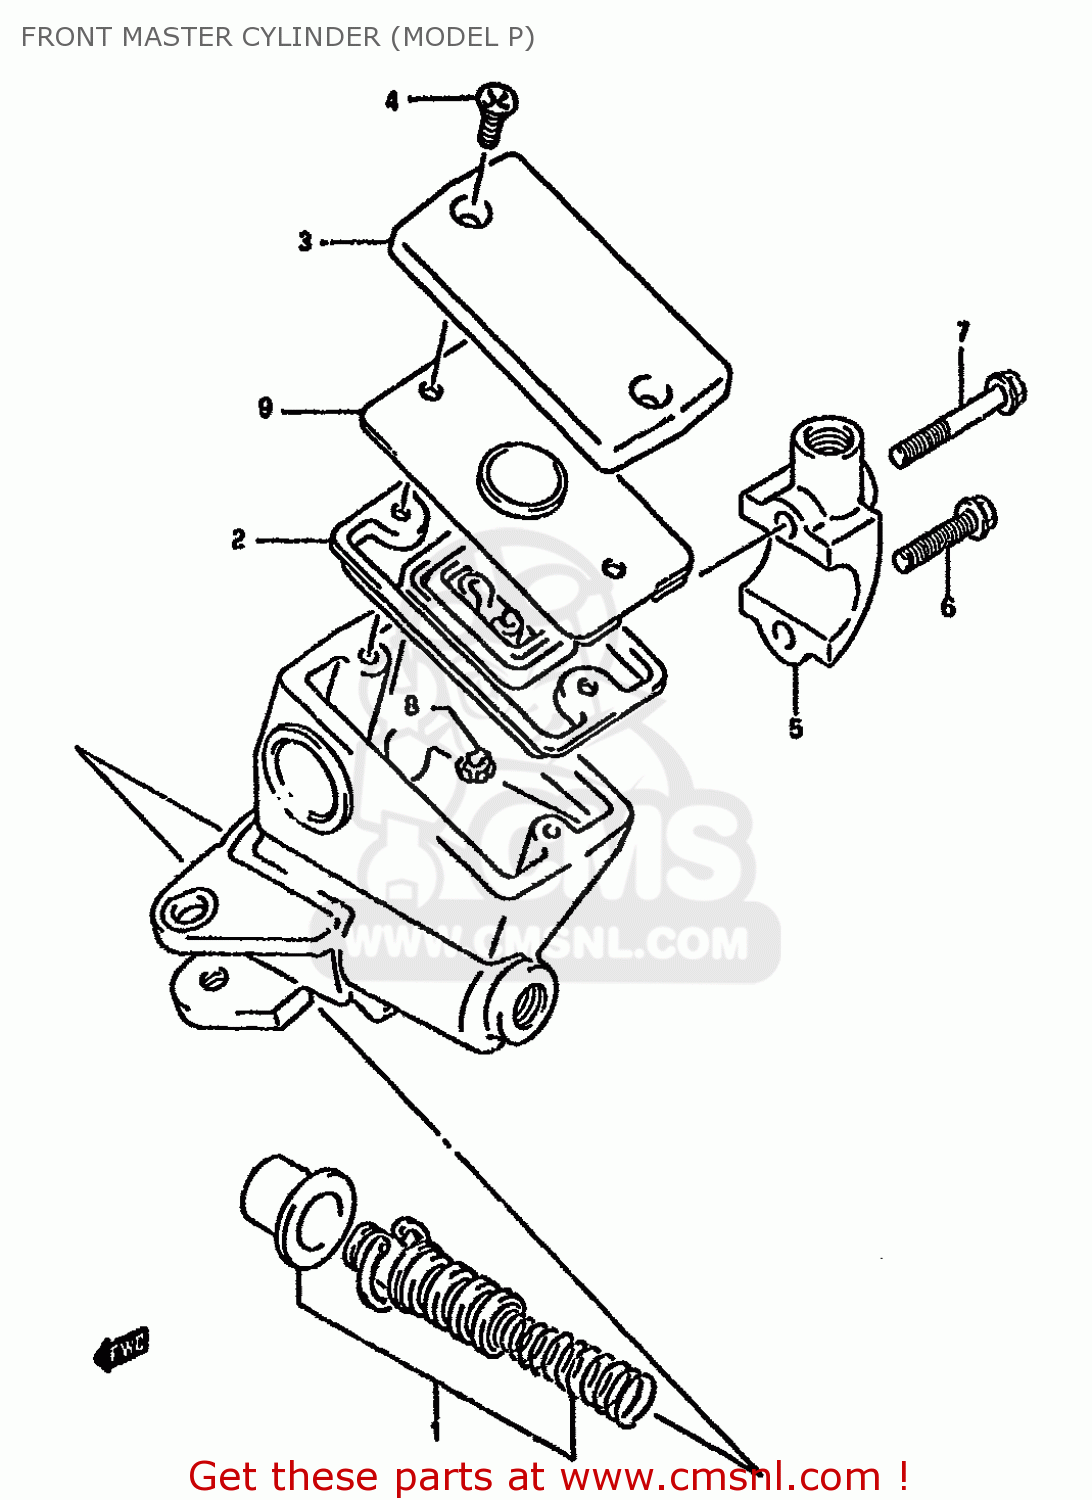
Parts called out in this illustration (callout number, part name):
1	PISTON & CUP SET
2	3
3	CAP
4	SCREW
5	HOLDER
6	BOLT(6X25)
7	BOLT(6X38)
8	PROTECTOR
9	PLATE,DIAPHRAGM
